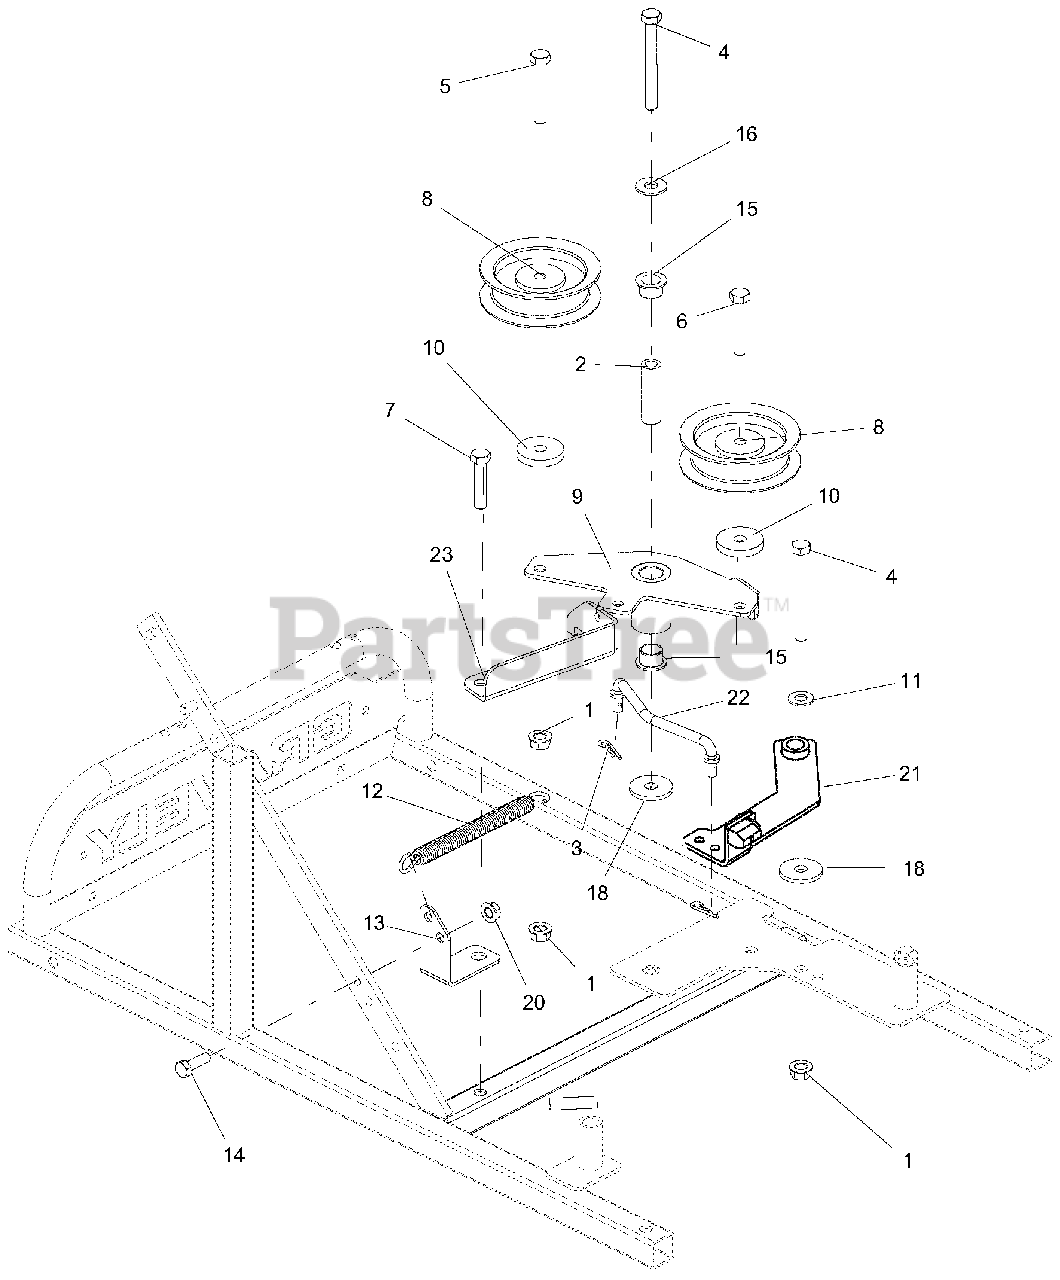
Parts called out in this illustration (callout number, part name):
1	NUT, LK-TOP-FLG .38-16 YWZC
2	BSHG-SLV .375X.625X2.03
3	PIN, HAIR INT .08X.18X1.18 YWZC
4	BLT-HEX .38-16X3.25 GR5 YWZC
5	BLT-HEX .38-16X2.25 GR5 YWZC
6	BLT-HEX .38-16X2.00 GR5 YWZC
7	BLT-HEX .38-16X1.75 GR5 YWZC
8	FLAT IDLER, STENS 280-671
9	WMT, IDLER ROCKER TM-26
10	WSHR-FL-STL .406X1.50X.245 YWZC
11	WSHR-FL-STL.406X.812X.065 YWZ
12	SPRG, EXTENSION
13	MOUNT, HWM PTO IDLER SPRING
14	BLT-HEX .31-18X1.00 GR5 YWZC
15	BSHG, FLANGE .625 x .75 x .50 x 1.00
16	WSHR-FL-STL.438X1.00X.083 YWZC
18	WSHR-FL-STL .406X1.375X.135 YZ
20	NUT, LK-TOP-FLG .312-18 YWZC
21	KIT, BRAKE ARM ASSY, HWM
22	ROD, SPINDLE BRAKE
23	MOUNT, LOWER PTO CABLE
